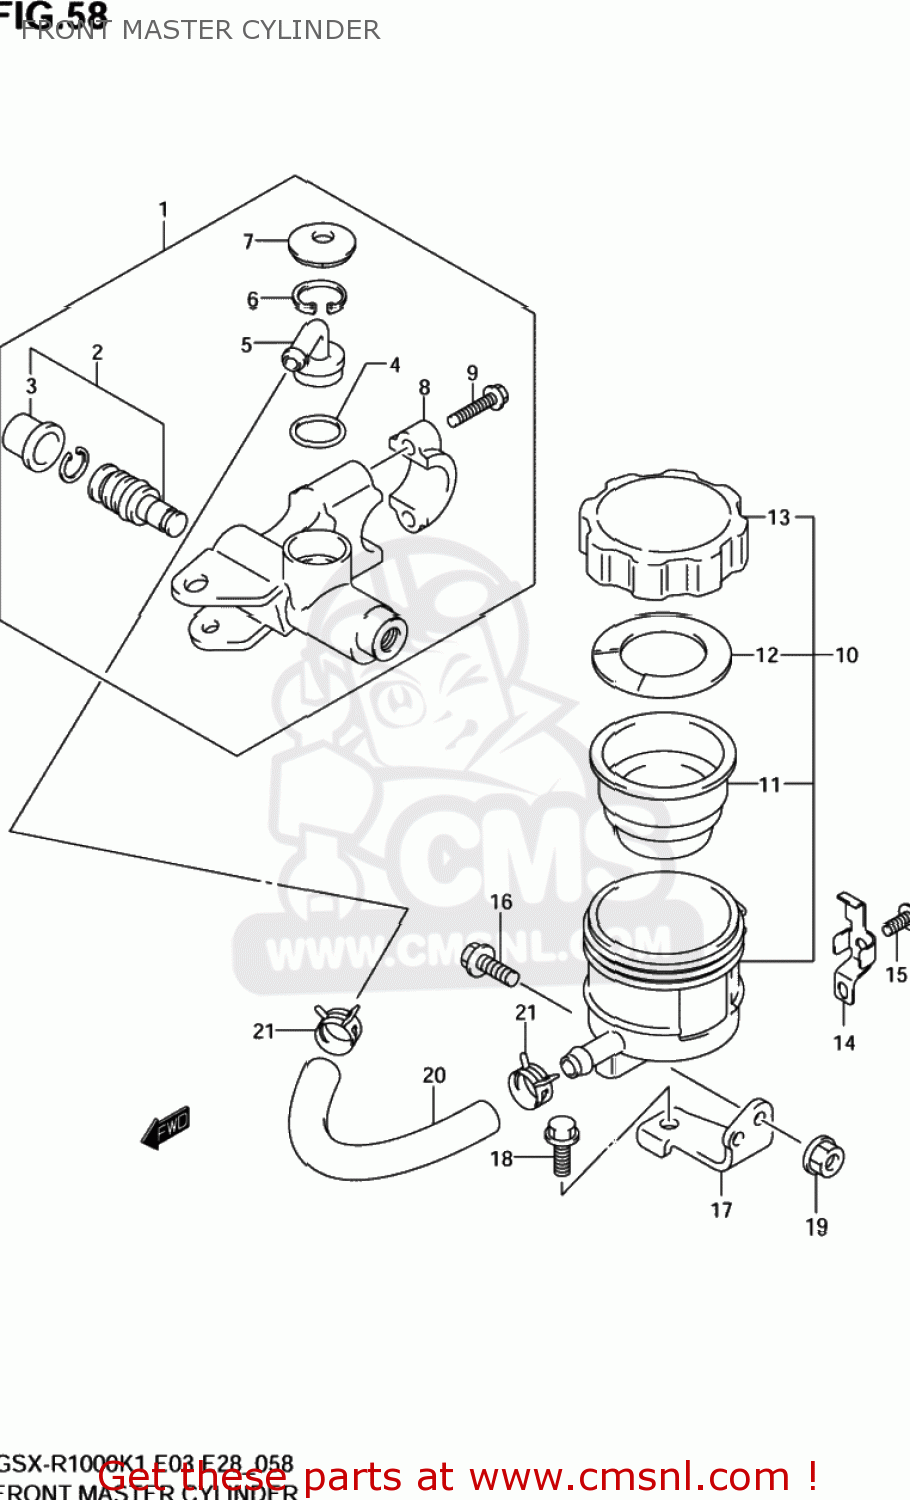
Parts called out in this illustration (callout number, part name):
1	CYLINDER ASSY,FR MASTER
2	PISTON & CUP SET
3	BOOT
4	O RING
5	CONNECTOR
6	CIRCLIP
7	COVER,DUST
8	HOLDER
9	BOLT(6X22)
10	TANK ASSY,RESERVOIR
11	DIAPHRAGM
12	PLATE,DIAPHRAGM
13	CAP
14	PLATE,RESERVOIR TANK CAP
15	SCREW
16	BOLT
17	BRACKET,RESERVOIR TANK
18	BOLT
19	NUT
20	HOSE,FR RESERVOIR TANK
21	CLAMP,RESERVOIR TANK FR
